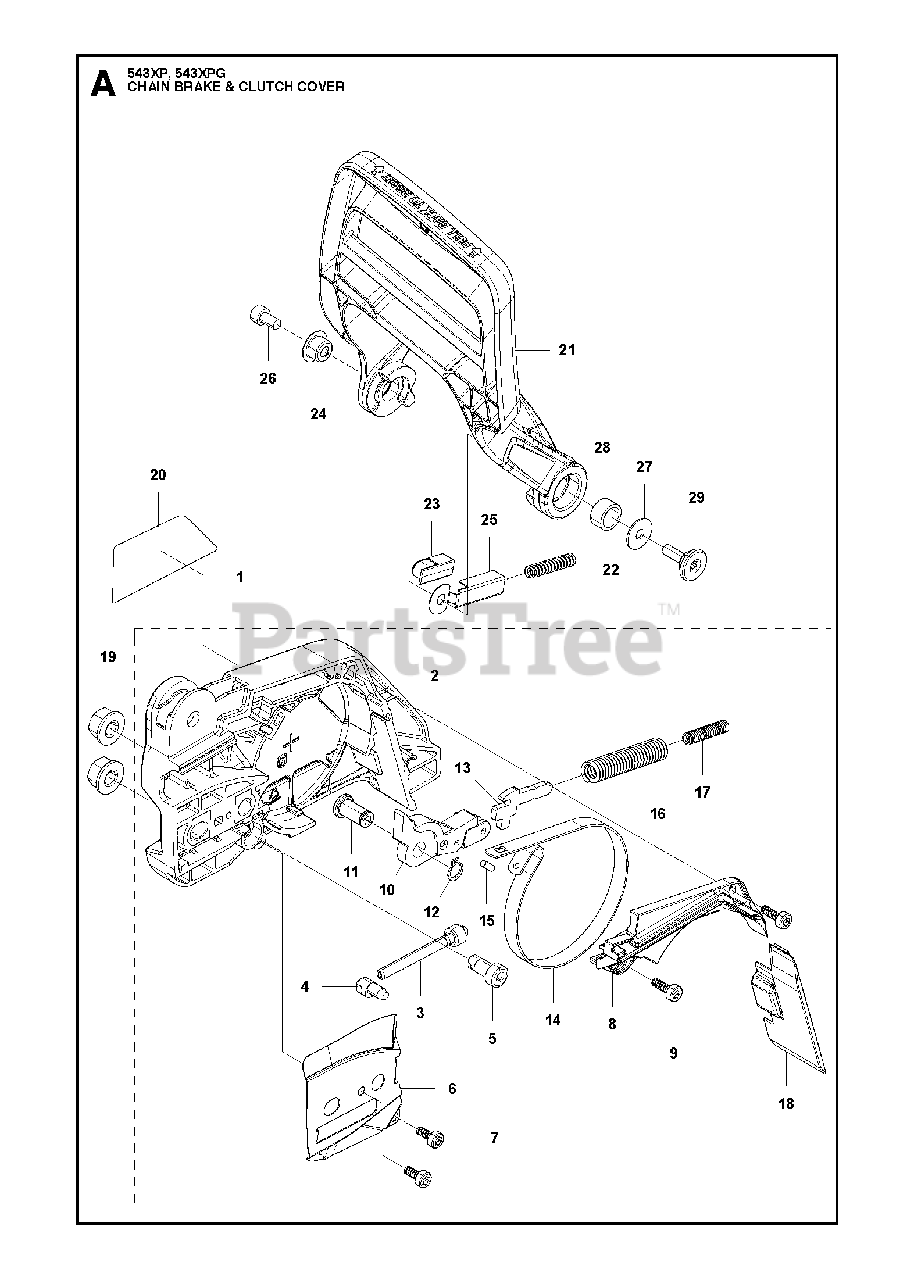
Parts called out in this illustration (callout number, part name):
1	CLUTCH COVER ASSY
2	CLUTCH COVER XC25
3	SCREW
4	NUT
5	GEAR
6	PLATE
7	SCREW
8	COVER LID
9	SCREW
10	BRAKE LEVER COMP
11	PIN
12	RING
13	ARM
14	BRAKE BAND
15	ROLLER
16	SPRING
17	SPRING
18	WEAR PROTECTION
19	NUT FLANGE
21	HAND GUARD
25	WEAR PROTECTION
26	BOLT
